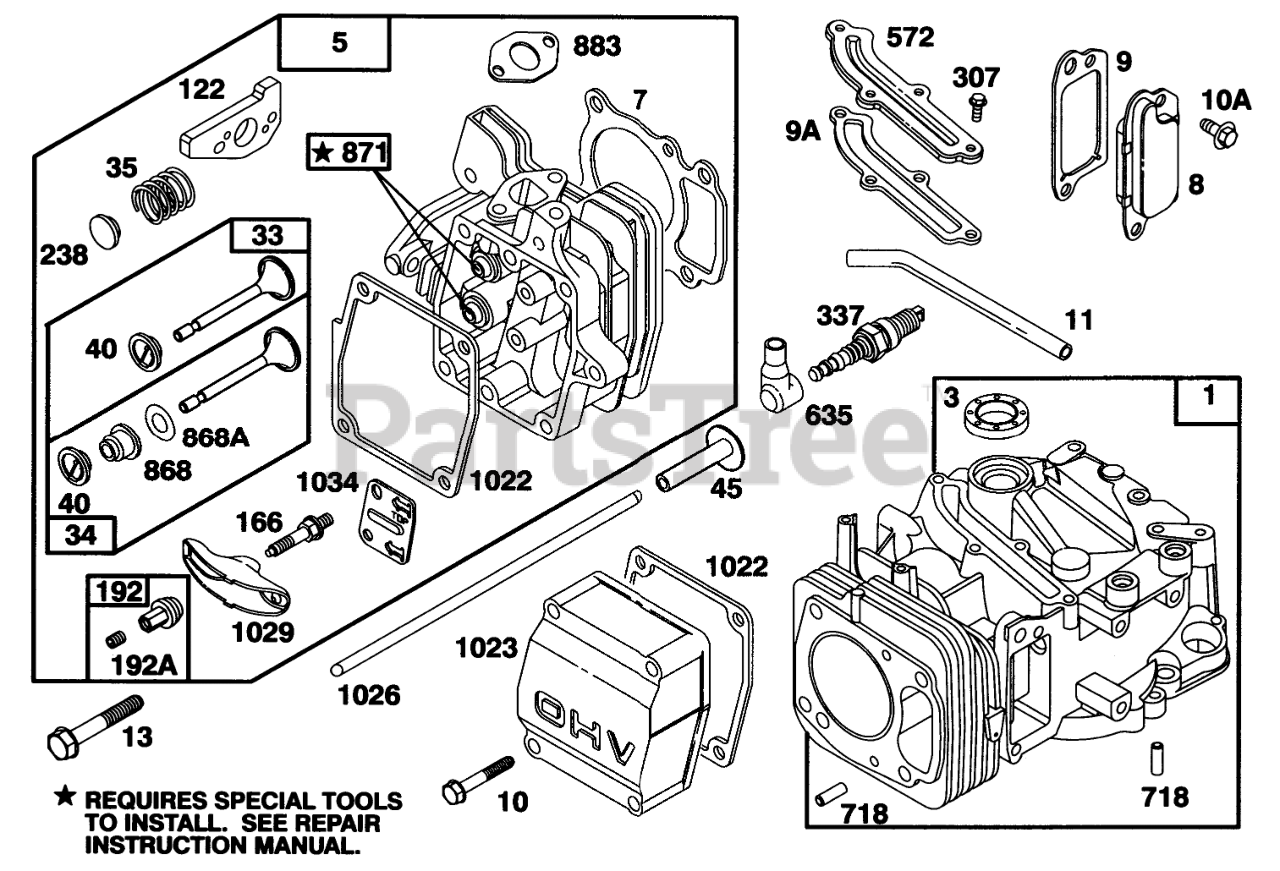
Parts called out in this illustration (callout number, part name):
1	CYLINDER ASSEMBLY
3	SEAL - OIL
5	CYLINDER HEAD
7	CYLINDER HEAD GASKET
8	BREATHER ASM
9	BREATHER GASKET
9A	GASKET-BREATHER
10	HEX HEAD SCREW
10A	HEX HEAD SCREW
11	BREATHER TUBE
13	CYLINDER HEAD SCREW
33	EXHAUST VALVE
34	INTAKE VALVE
35	VALVE SPRING
40	SPRING RETAINER
45	VALVE TAPPET
122	ADAPTER ASSEMBLY
166	ROCKER ARM STUD
192	NUT - HEX SPECIAL
192A	Screw-Set
238	VALVE CAP
307	SCREW - SEM
337	PLUG-SPARK
572	BAFFLE - CYCLINDER
635	SPARK PLUG ELBOW
718	DOWEL - SLEEVE
868	SealAssy-Valve
868A	Seal-Valve
871	Bushing-Guide
883	EXHAUST GASKET
1022	ROCKER COVER GASKET
1023	Cover-Valve
1026	PUSH ROD
1029	ROCKER ARM
1034	PUSH ROD GUIDE
